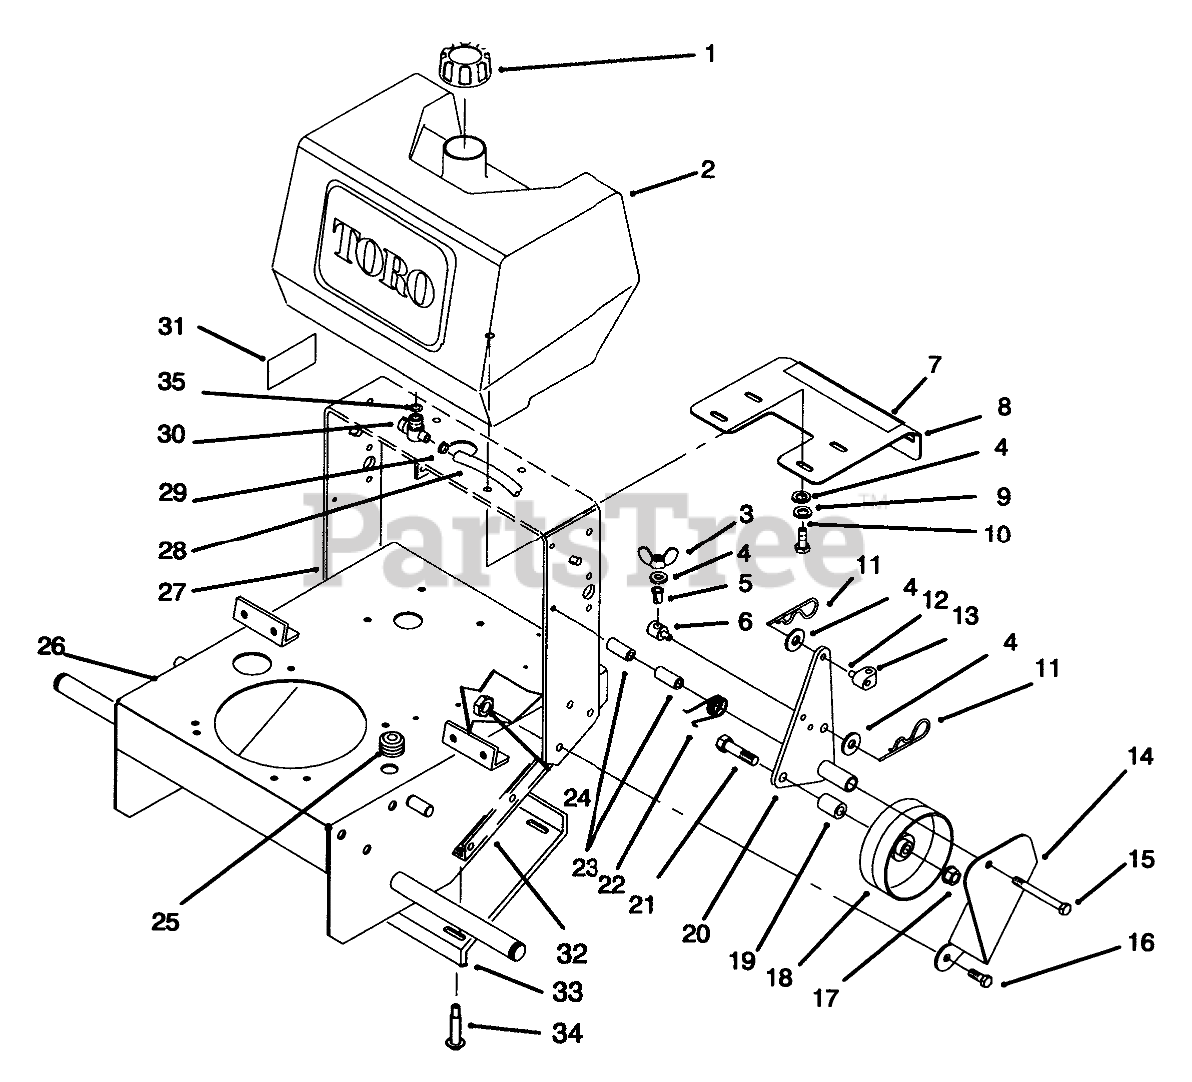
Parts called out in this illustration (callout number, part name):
1	GAS CAP ASM
2	FUEL TANK
3	NUT-WING
4	WASHER-PLAIN
5	BUSHING-NYLON
6	FITTING-ROD
7	DECAL - GROUND SPEED
8	Plate
9	WASHER-LOCK
10	SCREW-HH
11	PIN-COTTER
12	PIN-CLEVIS
13	FITTING-ROD
14	Bracket-LH
15	SCREW-HH
16	SCREW-HH
17	NUT-LOCK, NI
18	IdlerWheel
19	WHEEL IDLER SPACER
20	BRACKET-Idler, LH
21	SCREW-LEVELER
22	SPRING-TORSION, LH
23	SPACER-PIVOT, IDLER
24	NUT-LOCK, NI
25	GROMMET
26	Frame
27	Frame Rear
28	HOSE-FUEL
29	CLAMP-HOSE
30	VALVE-FUEL
31	DECAL-SHUT OFF, FUEL
32	Mount-Angle
33	Panel-Bottom
34	SCREW
35	O-RING
